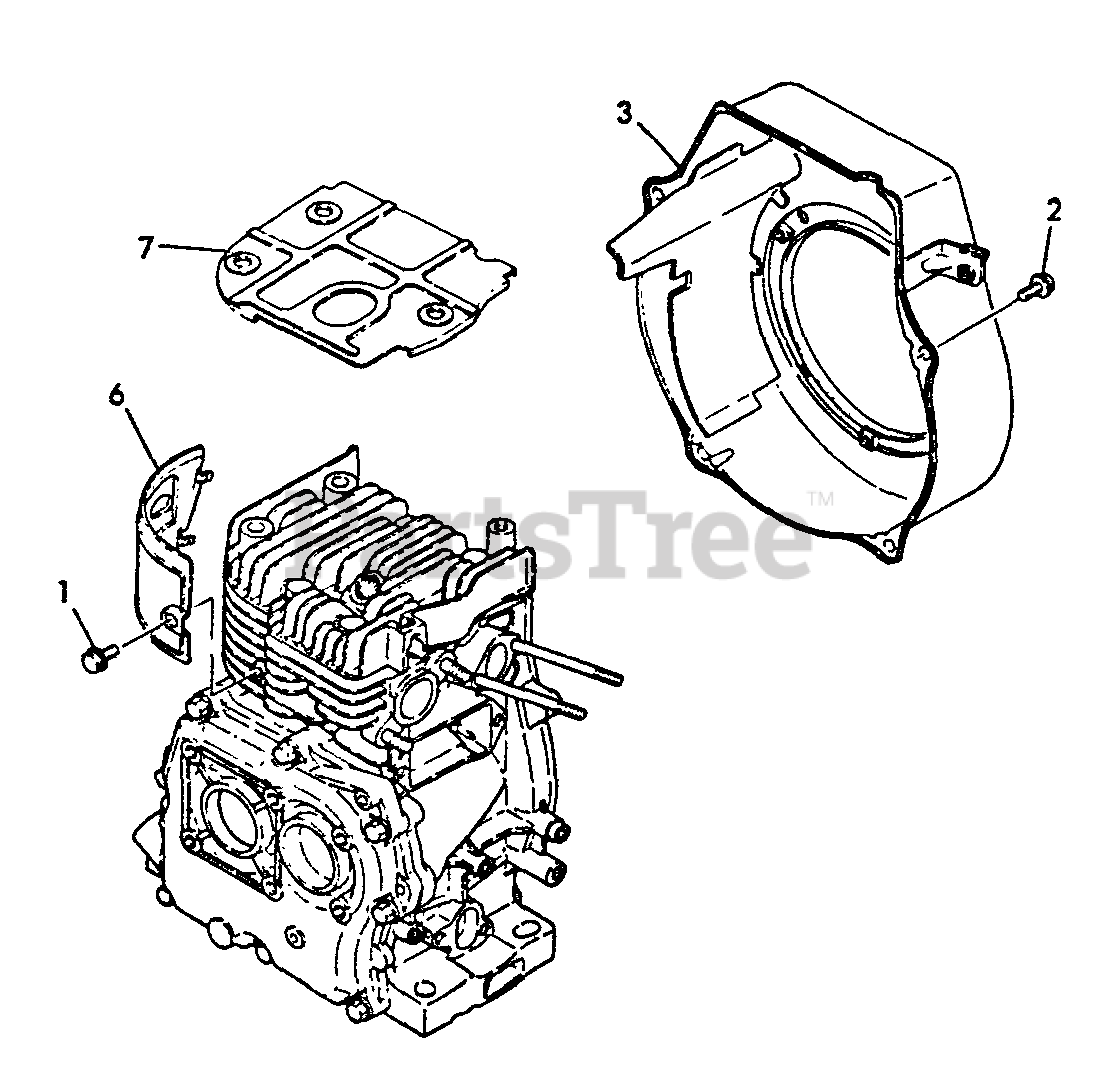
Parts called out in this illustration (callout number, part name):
1	BOLT - 6×8 -- PLATED
2	BOLT - 6×8 -- PLATED
3	COVER, FAN
6	PLATE
7	COVER, HEAD
